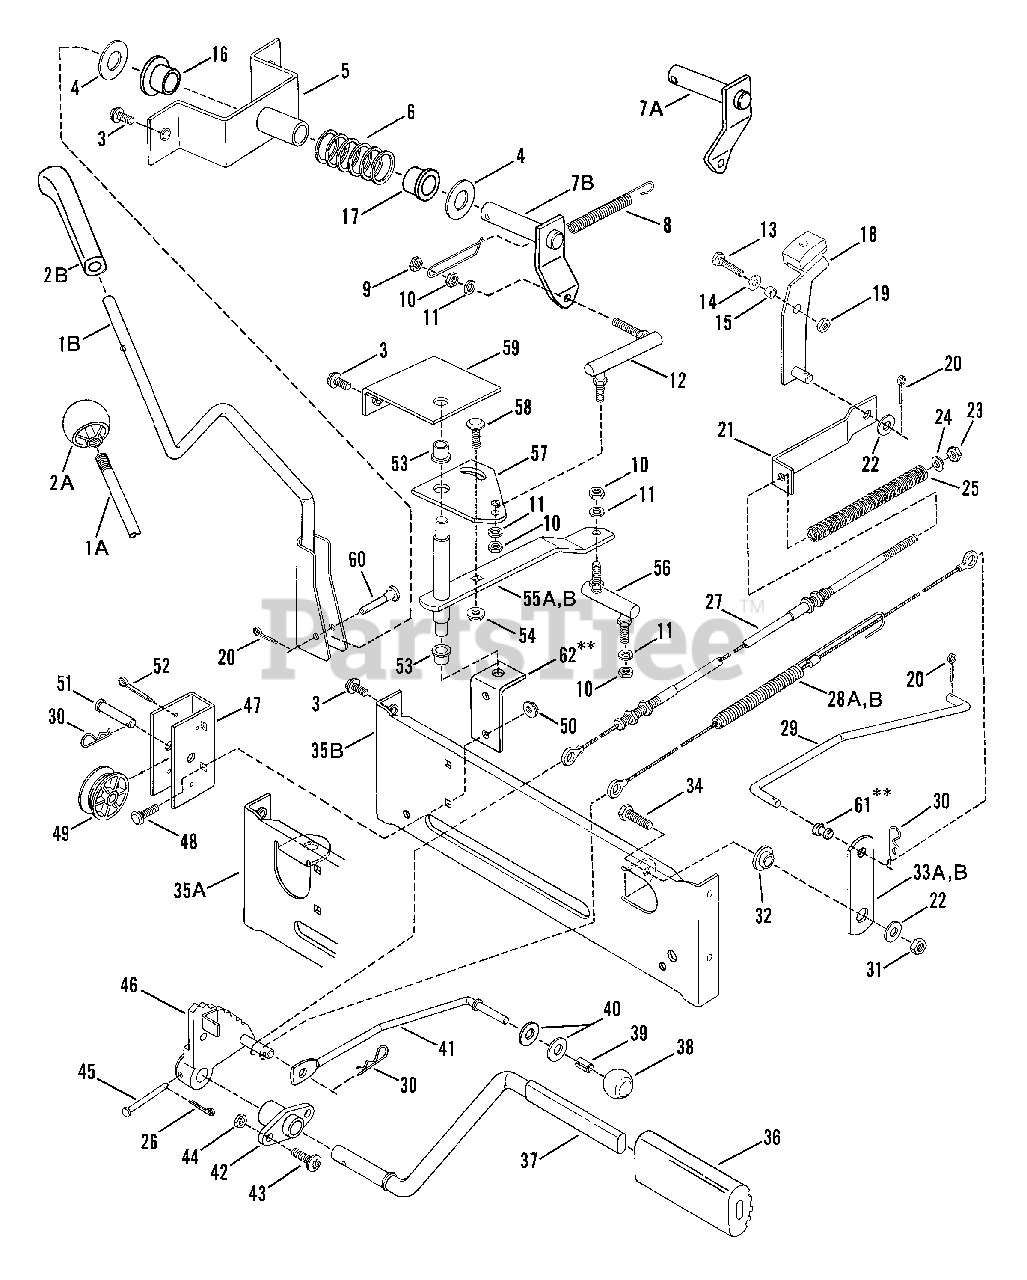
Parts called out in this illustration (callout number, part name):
1A	SHIFTER, Transmission (Threaded)
1B	SHIFTER, Transmission
2A	KNOB, Shifter (Round)
2B	KNOB, Shifter (Elongated)
3	SCREW, 5/16-18x1/2" Self-Tapping
4	WASHER, Thrust
5	PIVOT, Shifter
6	SPRING, Shift Detent
7A	ARM, Shifter
7B	ARM, Shifter
8	SPRING
9	LOCKNUT, 5/16-24 Hex
10	NUT, 5/16-24 Hex
11	LOCKWASHER, 5/16 Split
12	LINK, Shift
13	SCREW, 1/4-28x1" Hex Hd. Cap
14	WASHER, 1/4 SAE Flat
15	SPACER
16	BUSHING, 3/4-1.62 Flange
17	BUSHING, 3/4-1.0 Flange
18	LEVER, Brake Assm'y.
19	LOCKNUT, 1/4-28 Hex
20	COTTER-PIN, 3/32x3/4"
21	LINK, Brake
22	WASHER, 3/8 SAE Flat
23	LOCKNUT, 5/16-18 Hex
24	WASHER, 5/16 SAE Flat
25	SPRING, Brake Link
26	COTTER-PIN, 3/32x1"
27	CABLE, Brake
28A	CABLE, Clutch (22.5" Long)
28B	CABLE, Clutch (23.5" Long)
29	ROD, Clutch
30	PIN, Hair 1.12"
31	LOCKNUT, 3/8-24 Hex
32	SPACER
33A	ARM, Pivot
33B	ARM, Pivot
34	SCREW, 3/8-24x1" Hex Hd. Cap
35B	BRACE
36	PAD, Petal
37	PEDAL, Clutch/Brake
38	KNOB, Latch 5/16"
39	RING, Tolerance 5/16" x 1/2"
40	WASHER, Nylon 5/16"
41	LATCH, Clutch/Brake
42	PIVOT, Clutch/Brake Pedal
43	SCREW, 5/16-18x7/8" Torx
44	NUT, 5/16-18 Hex
45	PIN, Clevis, 3/16x1-1/2"
46	BRACKET, Pedal Pivot
47	BRACKET, Spool (No longer available)
48	BOLT, 1/4-20x3/4" Short Neck Carriage
49	SPOOL, Bracket
50	LOCKNUT, 1/4-20 Hex Flange
51	PIN, Clevis, 3/8x1-9/32"
52	COTTER-PIN, 1/8x1-1/4"
53	BEARING
54	LOCKNUT, 5/16-18 Hex Flange
55A	LEVER, Shift
55B	LEVER, Shift
56	LINK, Shift
57	LEVER, Shift Adjuster
58	BOLT, 5/16-18x3/4" Carriage
59	BRACKET, Shift
60	PIN, Clevis, 1/4x5/8"
61	BEARING, Nyliner
62	BRACKET, Pivot
